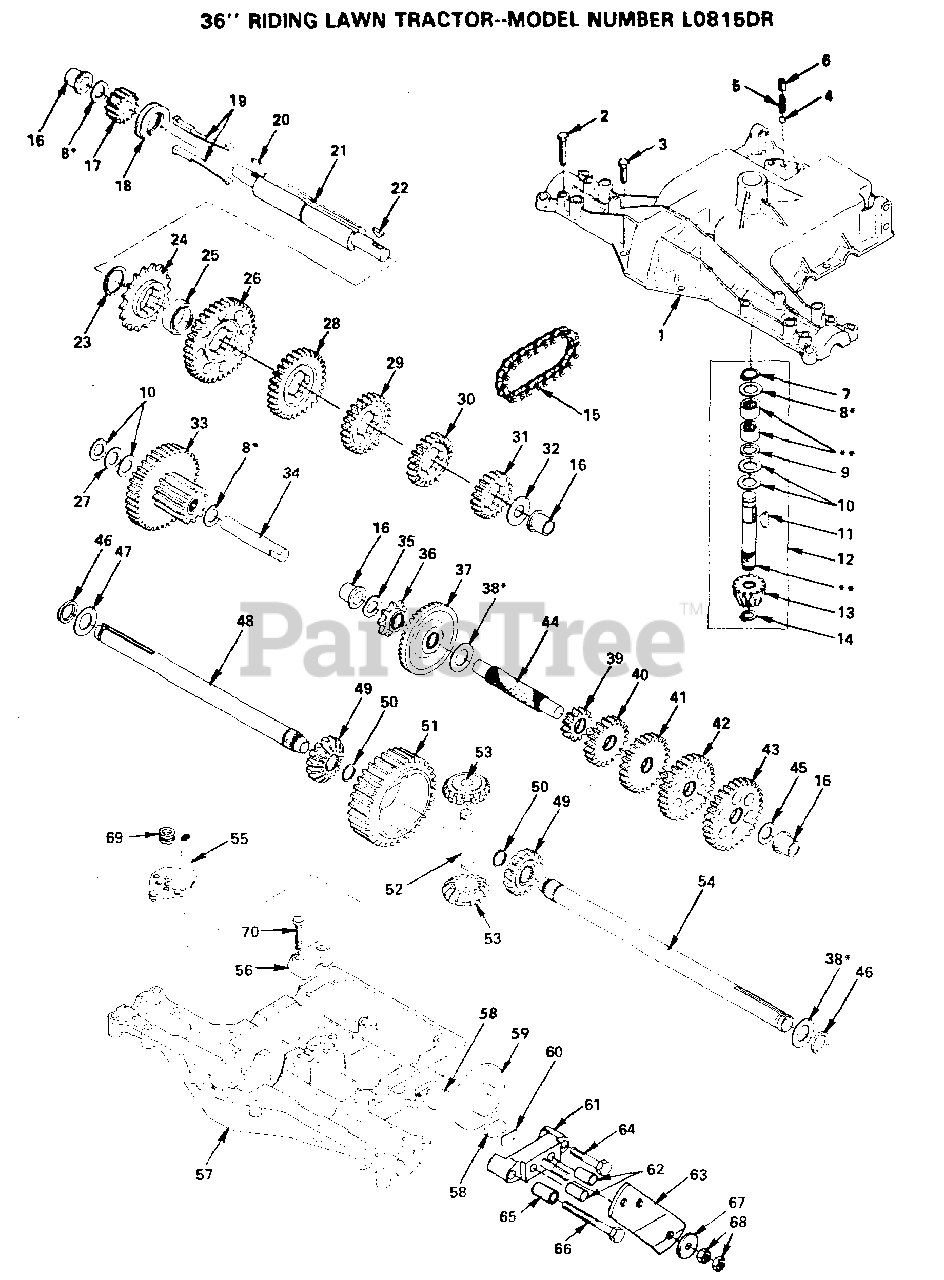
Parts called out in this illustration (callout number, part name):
1	HOUSING, UPPER
2	SCREW 1/4-20 X 1.31
3	SCREW 1/4-20 X .875
4	BALL DETENT
5	SPRING, DETENT
6	SCREW, SET
7	RING RETAINING
8	WASHER PLAIN
8A	WASHER, PLAIN .632 X 1.00 X .026
8B	WASHER PLAIN
8C	WASHER PLAIN
8D	WASHER PLAIN
8E	WASHER PLAIN
8F	WASHER PLAIN
8G	WASHER, PLAIN .632 X 1.00 X .060
8H	WASHER PLAIN
10	WASHER PLAIN
11	KEY WOODRUFF #9
12	ASSY KIT INPUT SHAFT
13	PINION BEVEL 14 TEETH
14	RING, RETAINING
15	CHAIN, 24 PITCHES
16	BEARING, FLANGE
17	GEAR SPUR, 14 TEETH
18	COLLAR CLUTCH
19	KEY, CLUTCH
20	KEY WOODRUFF #3
21	SHAFT, INTERMEDIATE
22	KEY, WOODRUFF, #61
23	RING, RETAINING
24	SPROCKET, 18T
26	GEAR, SPUR, 37 TEETH
27	SPACER .630 X 1.00 X .169
28	GEAR, SPUR 30T
29	GEAR, SPUR, 25 TEETH
30	GEAR, SPUR 22T
32	WASHER, PLAIN .640 X 1.37 X .061
33	ASSY, GEAR, COMB., 12T & 35T
34	SHAFT, IDLER
35	WASHER PLAIN
36	SPROCKET, 9 TEETH
37	GEAR, BEVEL 42T
38	WASHER PLAIN
38A	WASHER PLAIN
38B	WASHER PLAIN
38C	WASHER PLAIN
38D	WASHER PLAIN
38E	WASHER PLAIN
38F	WASHER, PLAIN .758 X 1.25 X .031
38G	WASHER PLAIN
38H	WASHER PLAIN
38I	WASHER PLAIN
38J	WASHER PLAIN
38K	WASHER PLAIN
38L	WASHER PLAIN
39	GEAR, SPUR, 12 TEETH
40	GEAR, SPUR 20T
41	GEAR, SPUR, 25 TEETH
42	GEAR, SPUR 28T
43	GEAR, SPUR, 31 TEETH
44	SHAFT, DRIVE
45	WASHER, PLAIN .632 X 1.00 X .060
47	WASHER, PLAIN .758 X 1.25 X .031
49	GEAR MITER 15T
51	GEAR, SPUR, 32T
52	SHAFT, CROSS
53	GEAR MITER 15T
55	ASSY SHIFTER
56	CAP, SUPPORT
57	HOUSING, LOWER
58	PUCK, FRICTION
59	DISC, BRAKE
61	ASSY, JAW, BRAKE
62	PIN, DOWEL
63	LEVER, ACTUATING
66	SCREW 5/16-18 X 2.50
67	WASHER, PLAIN .321 X 1.00 X .055
70	SCREW TAPPING
